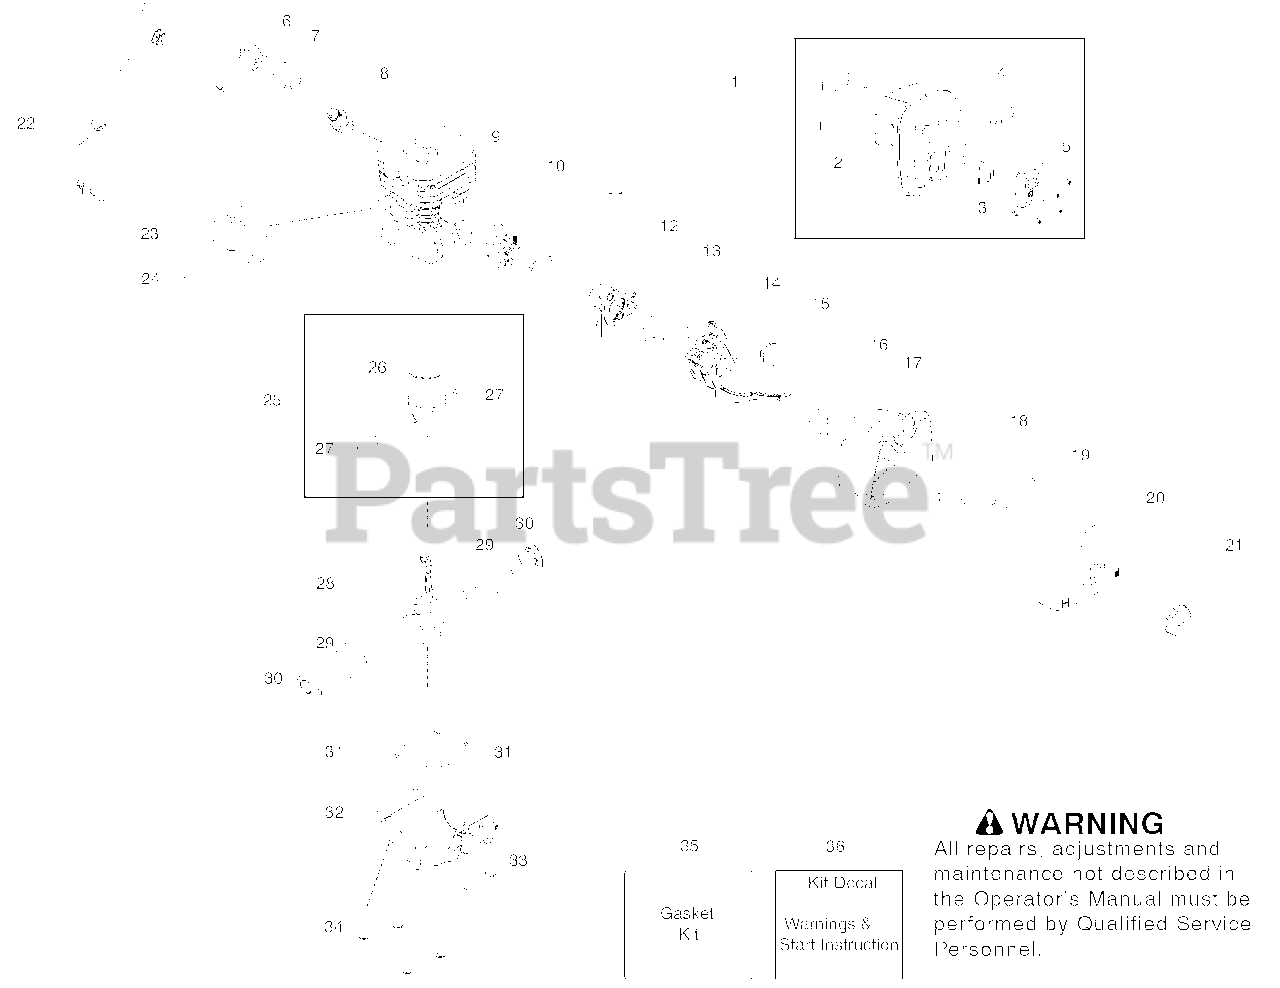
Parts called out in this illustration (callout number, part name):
1	Assy - Muffler
2	Gasket - Muffler (kit)
3	Kit - Spark Screen
4	Bolt - Muffler
5	Screw
7	Protector - Switch
8	Accy - Spark Plug (RCJ6-Y)
9	Cylinder - Chrome
10	Boot - Carb.
12	Plate - Carb.
13	Gasket - Carb. (kit)
14	Kit - Carb. (Zama W37)
15	Bulb - Purge
16	Gasket - Airbox (kit)
17	Base - Airbox
18	Nut - Carb screw
19	Filter - Air
20	Cover - Airbox
21	Assy - Airbox Knob
22	Assy - Leadwire
23	Module - Ignition
25	Kit - Piston
26	Ring - Piston
27	Retainer - Piston pin
28	Kit - Crankshaft
30	Kit - Crankshaft seal
31	Seal - Cylinder (kit)
32	Cap - Bearing
35	Kit - Gasket
36	Kit - Decal
